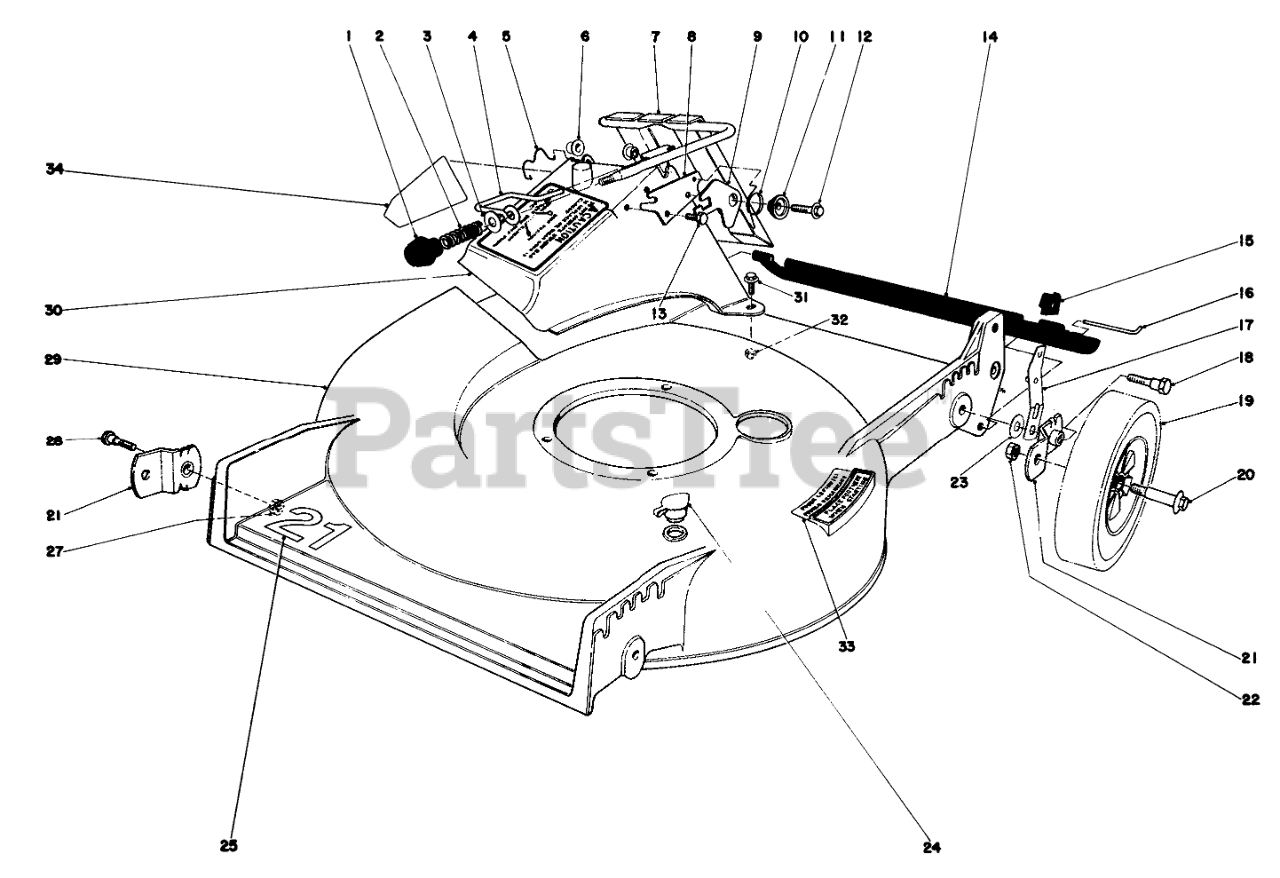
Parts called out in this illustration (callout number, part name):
2	COMPRESSION SPRING
3	WASHER
4	DOOR LATCH
5	DOOR RETAINER
6	BUSHING-NYLON
7	DOOR & HANDLE WA
8	DOOR LATCH PLATE
9	Latch Safety
10	TORSION SPRING
11	Latch Spacer
12	Screw
13	SCREW-HWH
14	SHIELD - TRAILING
15	KNOB-ARM
16	Rod Shield
17	SPRING ARM ASM (R&S)
18	5/16-18 PIVOT SCREW
19	WHEEL TIRE ASM 8 IN
20	BOLT-WHEEL
21	PIVOT ARM ASM A
22	Nut
23	WASHER-PIVOT
24	WASHOUT PLUG
25	Decal 21"
27	Nut
28	PIVOT SCREW
29	Deck
30	DISCHARGE CHUTE B
31	SCREW-HH
32	NUT-LOCK, NI
33	Decal-Place Foot Here
34	Decal-Attention
